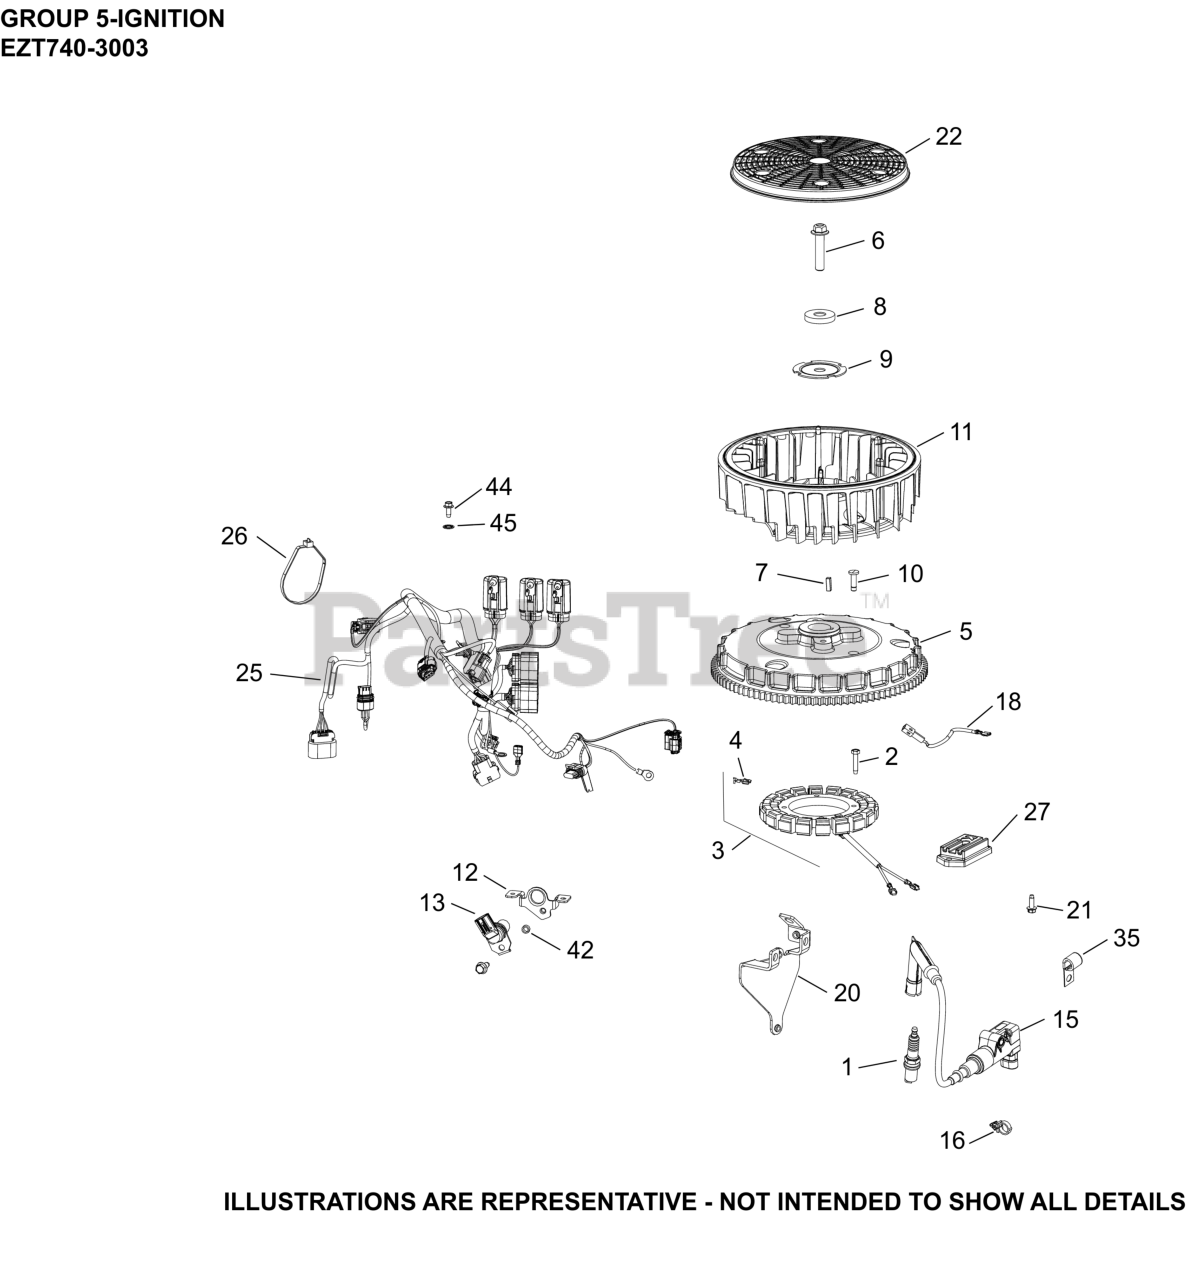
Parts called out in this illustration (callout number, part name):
1	SPARK PLUG, RFI
2	SCREW, THREAD FORMING
3	KIT, 15 / 20 AMP STATOR
5	FLYWHEEL, ASSEMBLY
6	SCREW, HEX FLANGE
7	KEY, SQUARE
8	WASHER, FLAT
9	PLATE, FAN MOUNTING
10	RETAINER, FLYWHEEL FAN
12	BRACKET, SENSOR
13	SENSOR, SPEED
15	COIL, IGNITION - EFI (RFI/EMC)
18	LEAD, REGULATOR RECTIFIER JUMPER
20	BRACKET, ECU
21	SCREW, THREAD FORMING
22	SCREEN, GRASS
25	HARNESS, W/TEMP SENSOR
27	REG/RECT (15AMP,HW,OVP)
35	CLIP, CABLE (KM)
44	SCREW, THREAD FORMING
45	WASHER, INT TOOTH LOCK #10
NI	MODULE, ECU
NI	SCREW, HEX FLANGE
